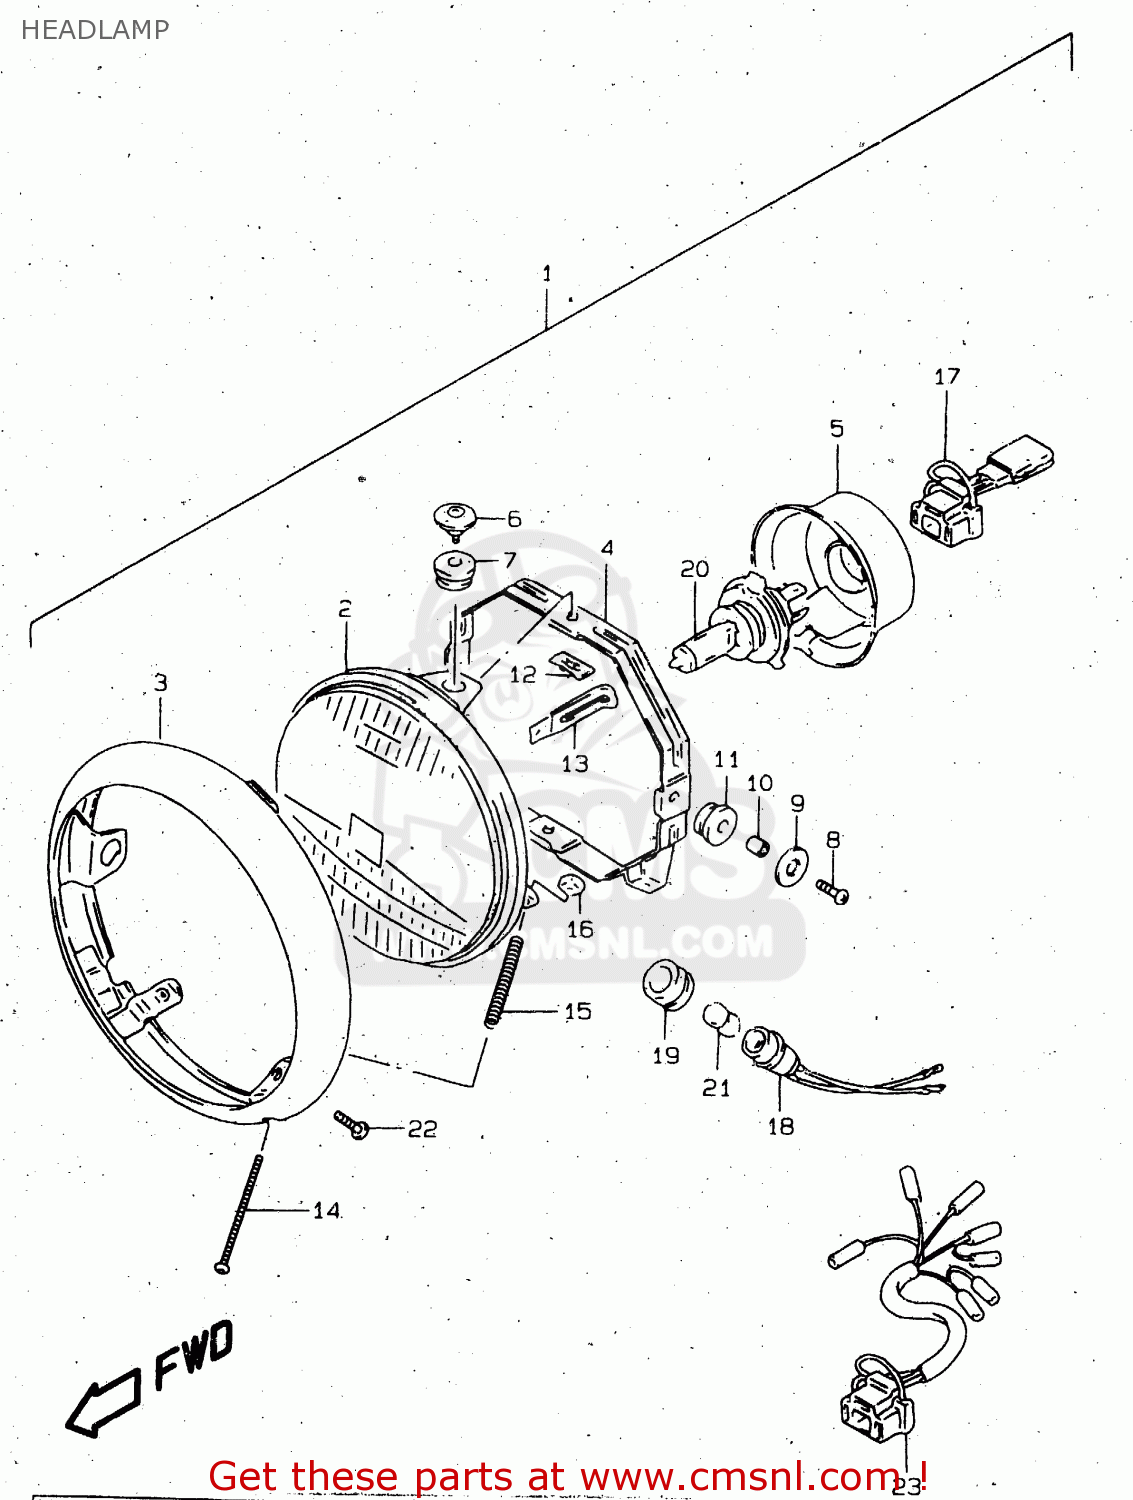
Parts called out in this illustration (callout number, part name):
1	HEADLAMP ASSY
2	LAMP UNIT
3	RIM
4	RING,MOUNTING
5	COVER,SOCKET
6	SCREW,MOUNTING
7	CUSHION
8	SCREW(5X14)
9	WASHER(5.5X18X1)
10	SPACER
11	CUSHION
12	NUT
13	CLAMP(L:65)
14	SCREW,ADJUSTING(4X50)
15	SPRING
16	NUT
17	SOCKET
18	SOCKET
19	JOINT,RUBBER
20	BULB(12V60/55W,H4)
21	BULB(12V3.4W,STANLEY,A72A)
22	SCREW
23	WIRE,HEADLAMP LEAD
